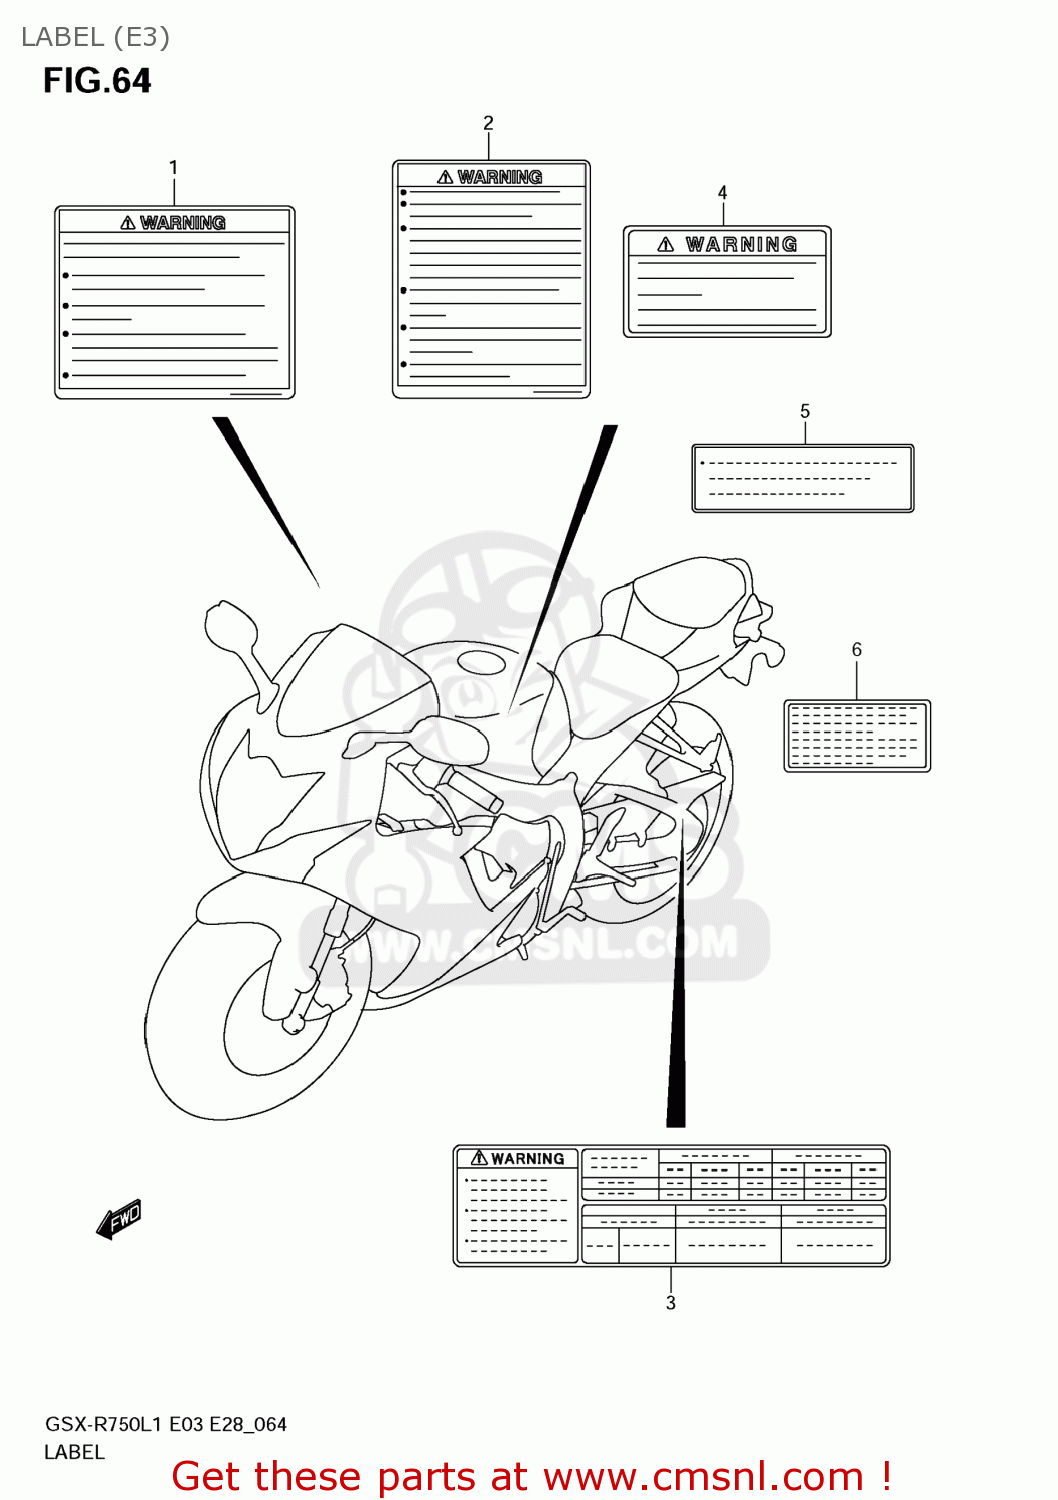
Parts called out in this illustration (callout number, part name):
1	LABEL,GENERAL WARNING
2	LABEL,SCREEN
3	LABEL,TIRE INFORMATION
4	LABEL,WARNING STEERING
5	LABEL,FUEL INFORMATION
6	LABEL,MANUAL NOTICE
7	MANUAL,OWNER'S
